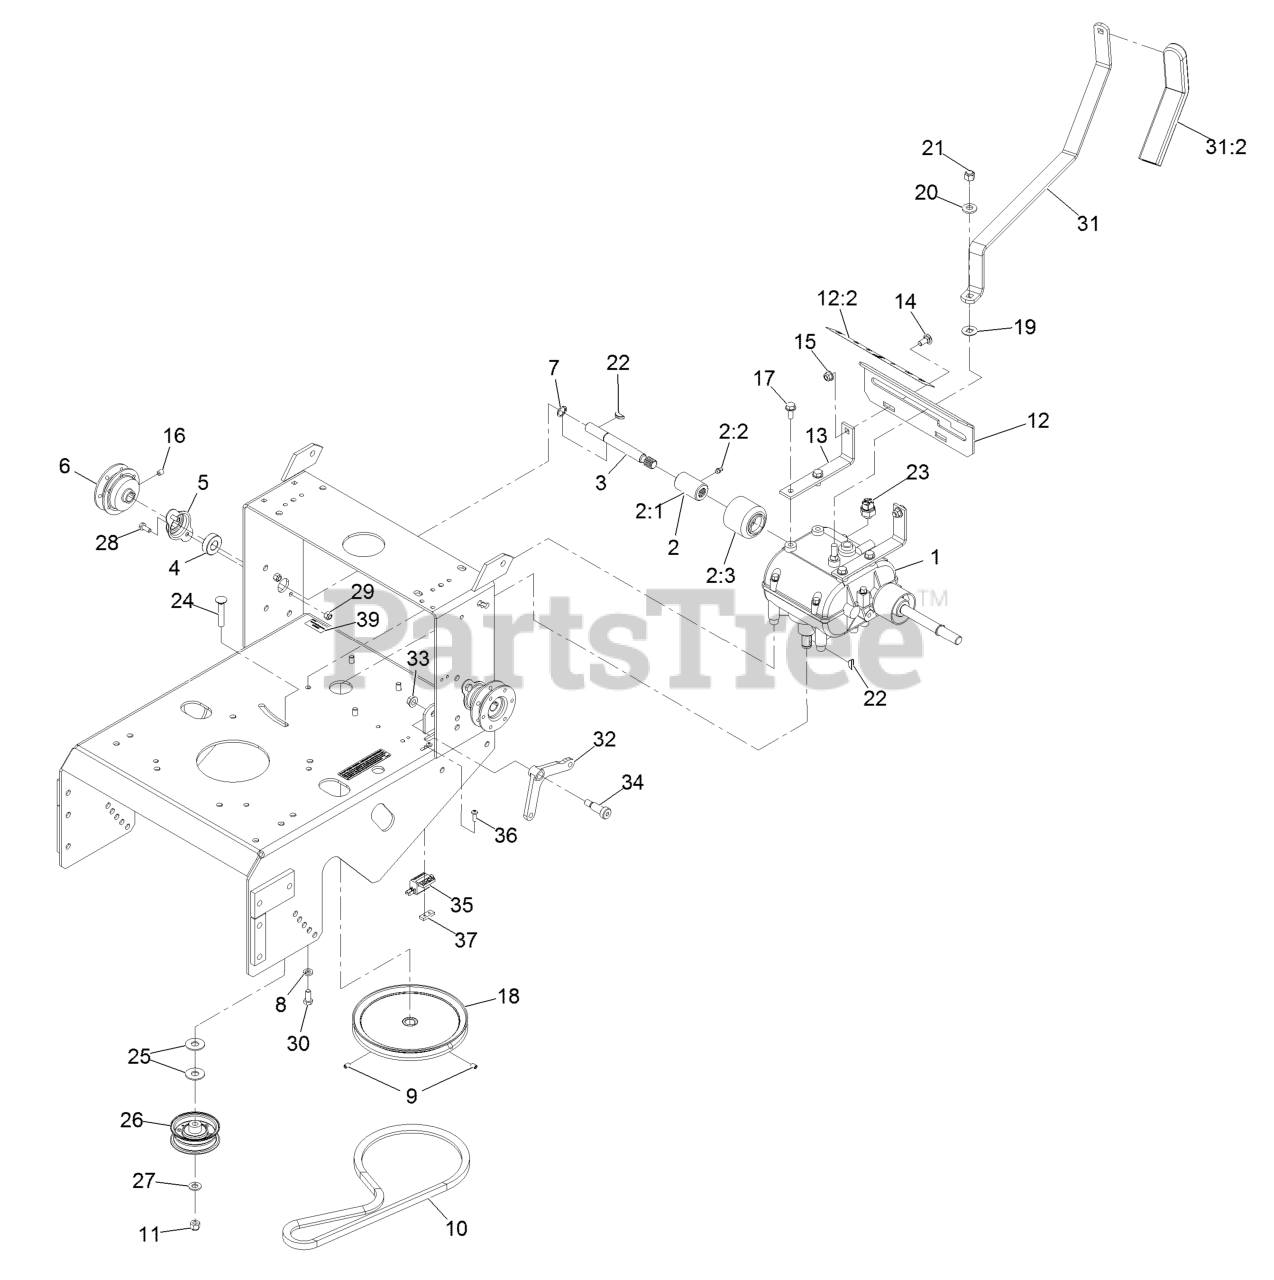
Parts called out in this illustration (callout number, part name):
2	ASM,COUPLER/ZERK
2:1	COUPLER
2:2	FITTING-GREASE
2:3	GUARD-COUPLER
3	SHAFT-TRANSMISSION
4	BEARING-SHAFT
5	FLANGE-OUTPUT
6	SHEAVE-TRANSMISSION
7	RING-RETAINING
8	WASHER-LOCK
9	SCREW-HSH
10	BELT,TRANS DRIVE
11	NUT-LOCK, NI
12	PLATE,SHIFTER W/DECAL
12:2	DECAL-SPEED, GROUND
13	BRACKET-PLATE, SHIFT
14	BOLT-CARR
15	NUT-HF, NI
16	SETSCREW
17	SCREW-THD ROLL, HWH
18	SHEAVE-TRANSMISSION
20	WASHER-BELLEVILLE
21	NUT-LOCK
22	KEY-WOODRUFF
23	SWITCH-START, NEUTRAL
24	SCREW-HH
25	WASHER-FLAT
26	PULLEY-IDLER, FLAT
27	WASHER-FLAT
28	SCREW-HH
29	NUT-LOCK, NI
30	SCREW-HH
31	ASM,SHIFT LEVER
31:2	GRIP,FOAM
32	BELLCRANK
33	NUT-HHF, WHIZ
34	BOLT-SHOULDER
35	SWITCH-OPEN, NORMALLY
36	SCREW-PPH
37	PLATE-TAPPED
39	Decal-Patent Ttco.Com
